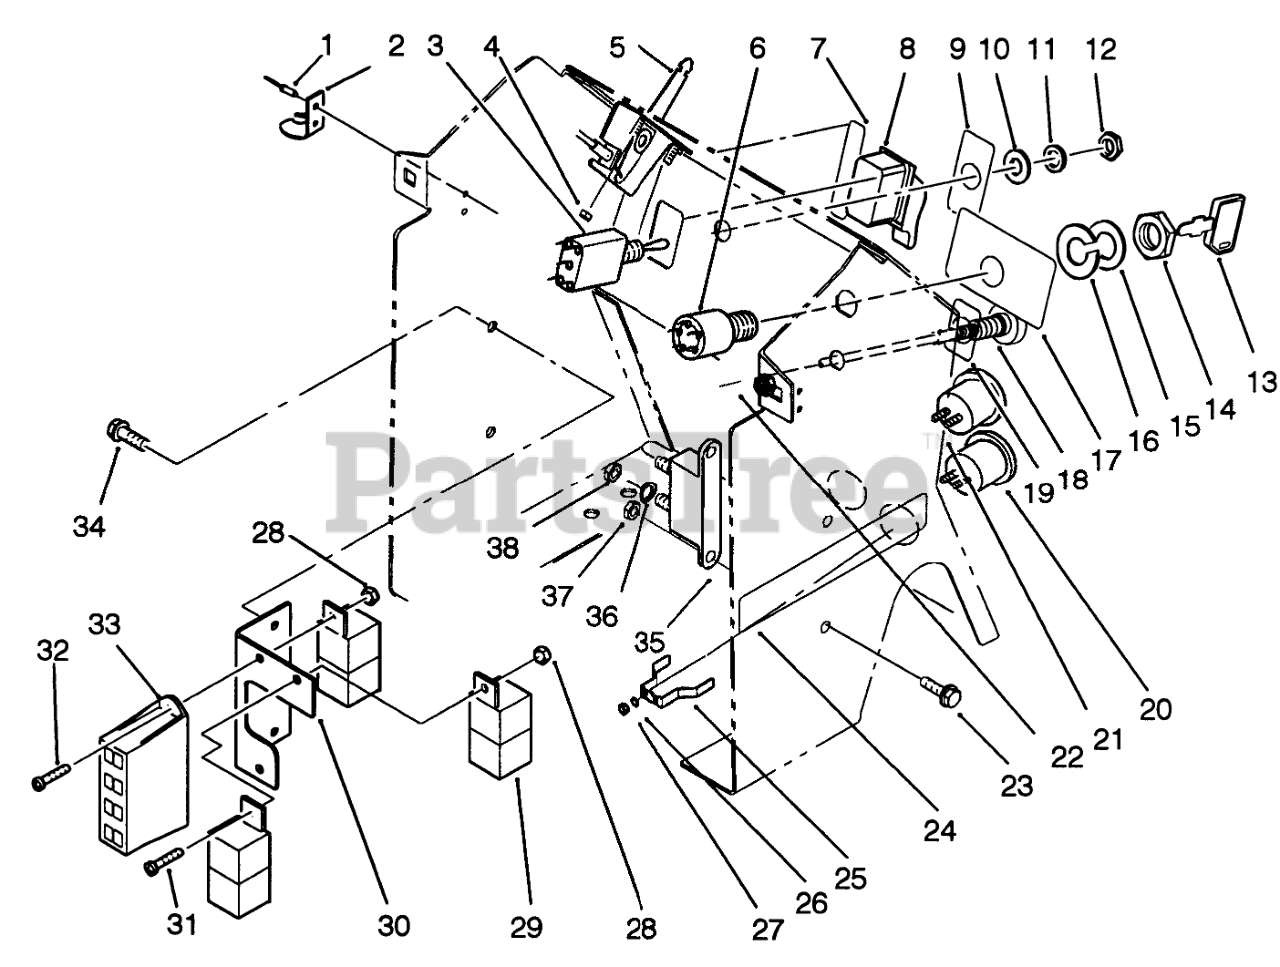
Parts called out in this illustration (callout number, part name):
1	POPRIVET 1/8X 1/8 BK
2	KEEPER-LATCH
3	Switch-Lights (Incl. Ref. #10-12)
4	Nut
5	CONTROL-THROTTLE
6	Switch-Ignition, Assembly (Incl. Ref #13-16)
7	DECAL-PTO
8	PTO-SWITCH W/COVER
9	DECAL-LIGHTS
10	TAB-WASHER
11	Washer
13	Key
15	Washer
16	LOCKWASHER
17	DECAL-IGNITION
18	CONTROL-CHOKE
19	DECAL-CHOKE
20	Meter-Hour (Incl. Ref. #20 & 23-25)
21	VOLTMETER
22	NUT-HJ
23	SCREW-HHF
24	DECAL-MODEL HYDRO
25	CLAMP-HOUR METER
26	WASHER-LOCK
28	Nut
29	RELAY
30	BRKT-FUSE HOLDER B
31	SCREW-PPH
32	SCREW
33	FUSE-HOLDER 4 WAY
34	TRS-1/4-20X1/2 BLACK
35	Solenoid
36	WASHER-LOCK
37	NUT-HEX
38	NUT-JAM
